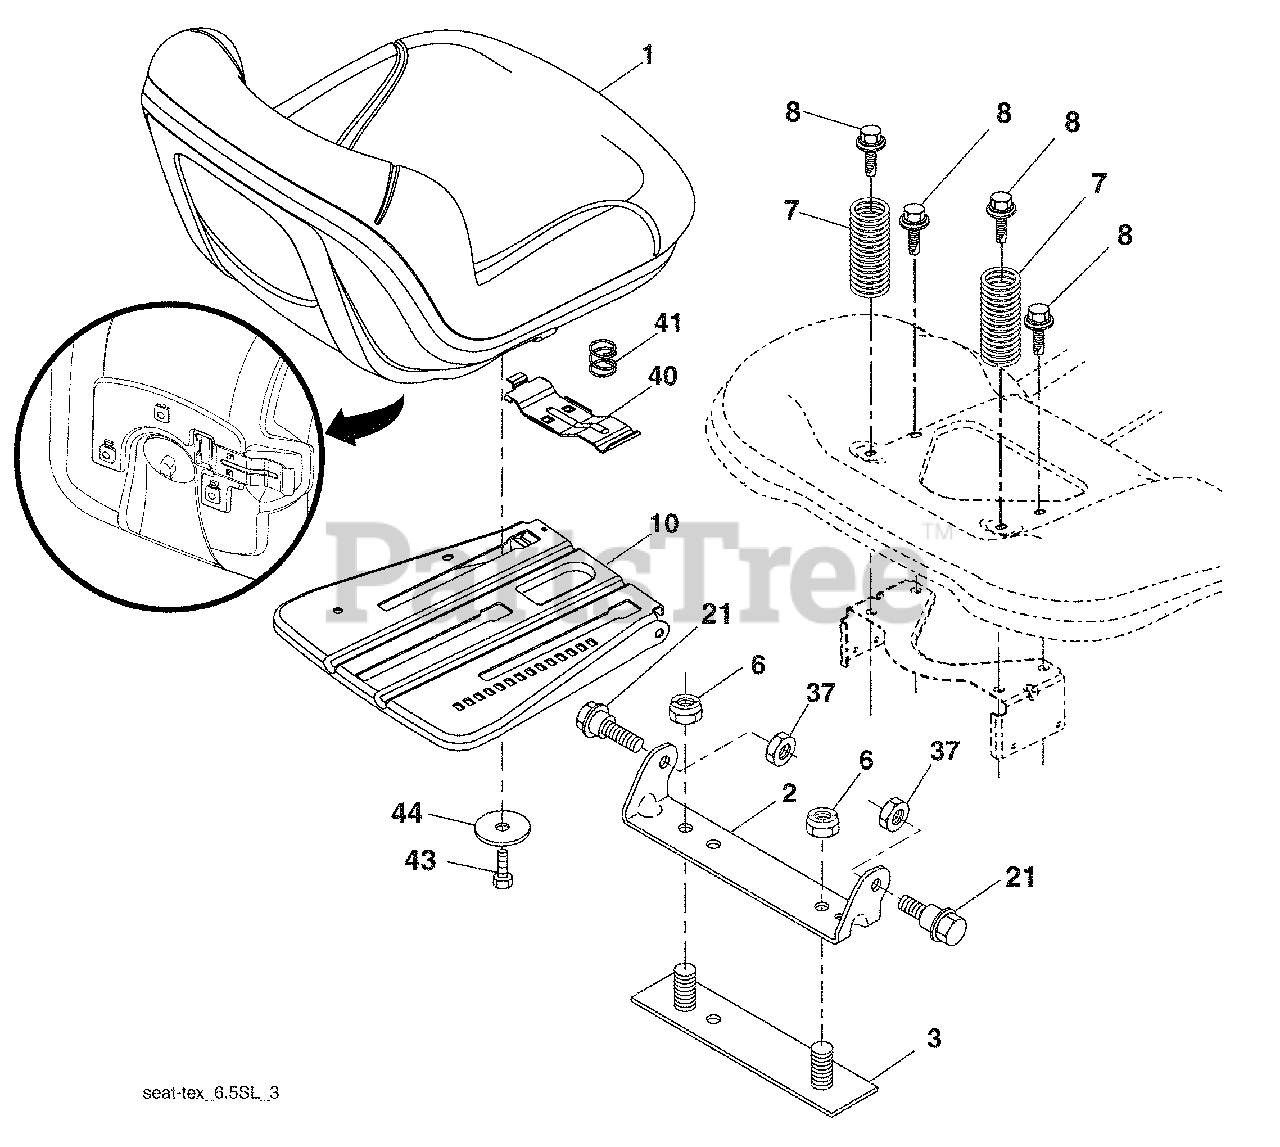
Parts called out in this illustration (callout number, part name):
1	Seat
2	Bracket Pivot Fender
3	Strap, Asm Fender
6	Nut, Lock w/Ins. 3/8-16 unc
7	Spring, Seat Cprsn
8	Bolt 5/16-18 unc x 3/4 w/Sems
10	Pan, Seat
21	Bolt, Shoulder 5/16-18
37	Nut, Lock 5/16-18 unc
40	Handle Slide Seat
41	Spring Latch Seat
43	Bolt Fin Hex 3/8-16 unc x 3/4
44	Washer 13/32 x 2-3/8 x 12 Ga.
